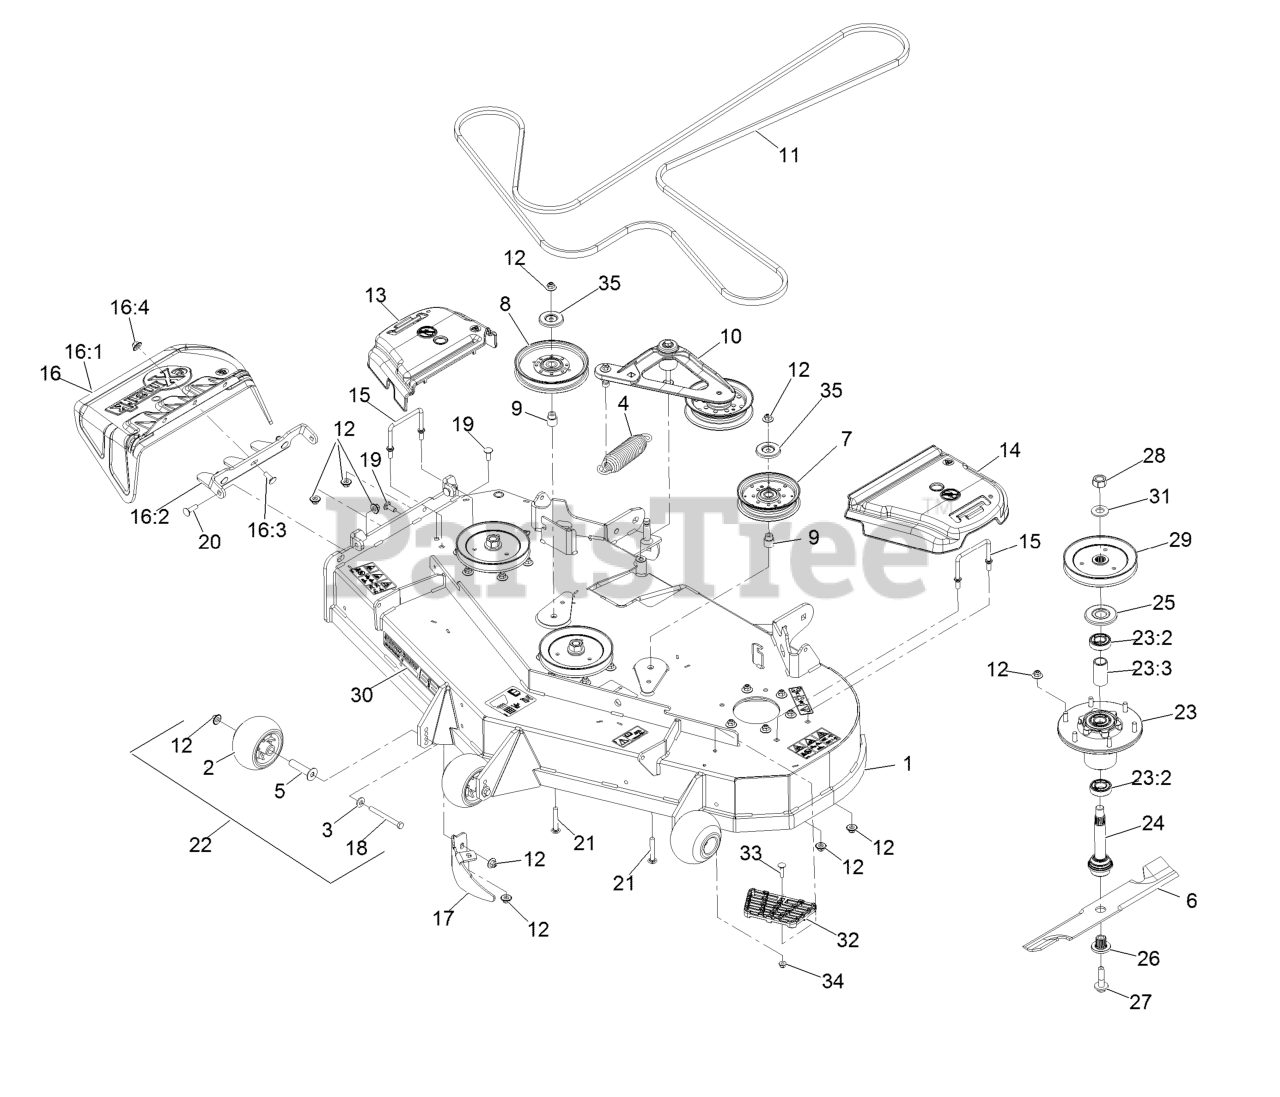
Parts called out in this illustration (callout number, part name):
1	ASM,Deck W/ Decals 52
2	Roller-Anti-Scalp
3	Washer-Spring Disc 3/8
4	Spring-Extension
5	Axle, Roller
6	Blade, Solid
6	Blade, Low Lift
6	Blade, Mulching
6	Blade-Notched
6	Blade-Extreme 2, 18.00"
7	Pulley-Idler, Flat
8	Idler-Pulley
9	Bushing, Idler
10	Deck Idler ASM
11	Belt,V-B X 186.00"
12	Nut-Nyloc 3/8-16 Flg
13	Cover-Belt, RH
14	Cover-Belt, LH
15	Wireform-Cover
16	ASM,Discharge Chute
16:1	Chute, Discharge
16:2	Bracket,Discharge Chute
16:3	Bolt-Carriage 3/8-16 X 1
16:4	Nut-Nyloc 3/8-16 Flg
17	Baffle-Dogleg, Lz-Vt52
18	Screw-HH 3/8-16 X 3 3/4 GR 8
19	Bolt-Carriage 3/8-16 X 1
20	Bolt-Carriage 3/8-16 X 1 1/4
21	Bolt-Carriage 3/8-16 X 2 1/2
22	Kit, Anti-Scalp Roller
23	ASM-Cutter Hsg With Bearings
23:2	Bearing-Ball
23:3	Spacer-Bearing
24	ASM-Spindle And Seal
25	Guard,Bearing Top .989
26	Bushing, Splined
27	Screw-Sems 1/2-20 X 2.19
28	Nut-Hex
29	Sheave,Blade Drive 6.50
30	Decal, 524
31	Washer-Spring Disc 3/4
32	Step-Deck
33	Bolt-Carriage 5/16-18 X 1 1/4
34	Nut-Nyloc 5/16-18 Flg
35	Shield-Dust
